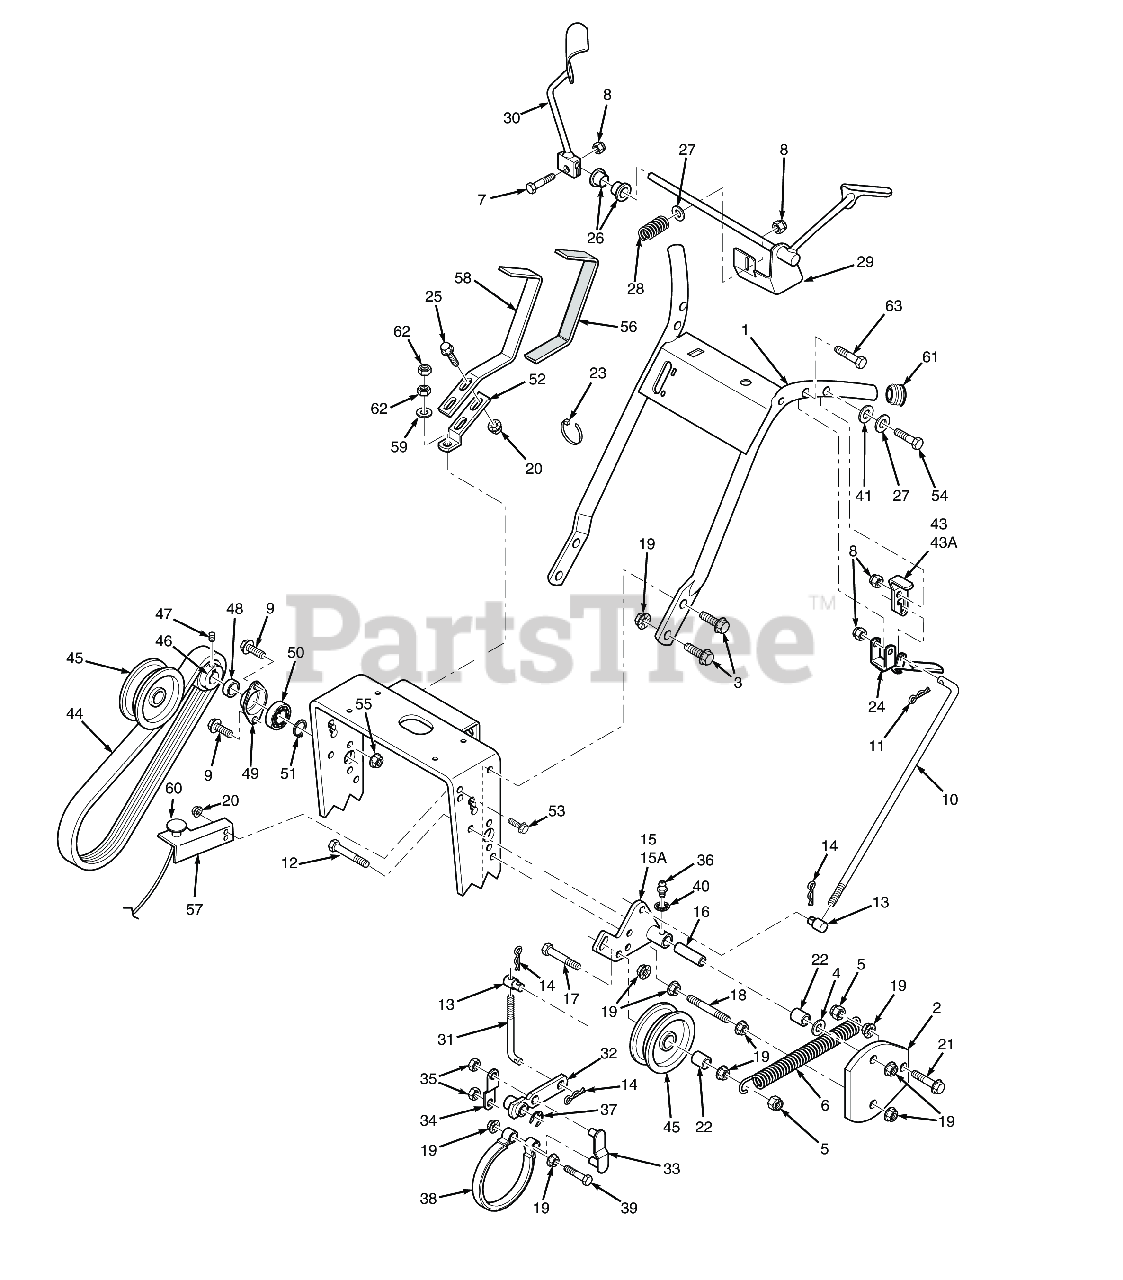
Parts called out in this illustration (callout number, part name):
1	Handle Assembly
2	Capscrew, 3/8-16 x 1.0" Serrated Flange Hex Hd
3	Flatwasher, 3/8" Special (.391 x .938 x .105)
4	HEX NUT, ELASTIC STOP LOCK, 3/8-16
5	Spring,Counter Balance
6	Bolt, 5/16 - 18 x 1 - 1/4" Hex Head
7	HEX NUT, ELASTIC STOP LOCK, 5/16-18
8	Bolt, Serrated Flange Hex Head 1/4 x 20 x 3/4"
9	Control Rod, Steering
10	HAIR PIN, .08 DIAMETER X 1-3/16"
11	Bolt, 3/8 - 16 x 4 - 1/2" Hex Head
12	SWIVEL JOINT, SPEED CONTROL ROD
13	COTTER PIN, HAIR - 0.94 X 1.62
14	Idler Bracket, RH
15	Idler Bracket, LH
15A	IDLER SLEEVE
16	Capscrew, Hex Head 3/8-16 x 3.25"
17	SUPPORT BELT GUARD
18	NUT, 3/8-16 SERRATED FLANGE HEX HEAD
19	Nut, Serrated Flange 5/16-18 (Right Front Engine Mounting, Briggs and Kohler Only)
20	CAPSCREW, 3/16 X 1-1/4" SERRATED FLANGE
21	Spacer, Idler
22	Cable Tie, .19 x 8.0"
23	Lever, Steering Control
24	Cpscrw, 5/16-18 x 1"Serrated Flange Hex Head
25	Bushing
26	Flatwasher, 5/16-.375 x .875 x .083 (35BV & 37BV-EFI)
27	Spring, Operator Presence
28	Operator Presence Lever, LH
29	Operator Presence Lever, RH
30	BRAKE ROAD
31	BRAKE LEVER
32	Link Weldment, Brake
33	BRAKE LINK PLATE
34	Nut, 3/8 Push - on
35	Greese Fitting, Straight 1/4 - 28
36	RETAINING RING, 5/8" EXTERNAL "E"
37	Brake Band Assembly
38	Capscrew, Hex Head 3/8-16 x 2.0"
39	1/4" INTERNAL TOOTH LOCKWASHER
40	Socket Head Capscrew #8-32 x 1/2"
41	Socket Head Capscrew #8 - 32 x 1/2"
42	Neutral Latch-RH 461241 Neutral Latch-LH
43	Neutral Latch Assembly, LH
43A	BELT, WHEEL DRIVE
44	Idler Pulley, Wheel Drive
45	Idler Pulley, Wheel Drive
46	Pulley, Jackshaft
47	Setscrew, Hex Socket Knurl Cup Pt. 5/16 - 18 (nylock)
48	SPACER, JACKSHAFT PULLEY
49	FLANGE, JACKSHAFT BEARING
50	BEARINGS, BALL, NEUTRAL RETURN
51	RETAINING RING, 5/8 EXT. - BASIC
52	Shift Lever
53	Capscrew, 5/16-18 x .75 Serrated Flange Hex Head
54	Bolt, Hex Head 5/16-18 x 2-1/2" (x3) (35BV & 37BV-EFI)
55	NUT, 1/4-20 SERRATED FLANGE HEX HEAD
56	Grip, Shift Handle
57	Bracket, Choke Mounting
58	Shift Lever Extension w/Grip
59	Flatwasher, 3/8" Special (.391 x .938 x .105)
60	Choke Control
61	Plug, Handle Bar
62	HEX NUT, 3/8-24 R.H. THREAD
63	Bolt, Hex Head 5/16-18 x 2-1/2" (35BV & 37BV-EFI)
64	Cap, Fuel Tank
